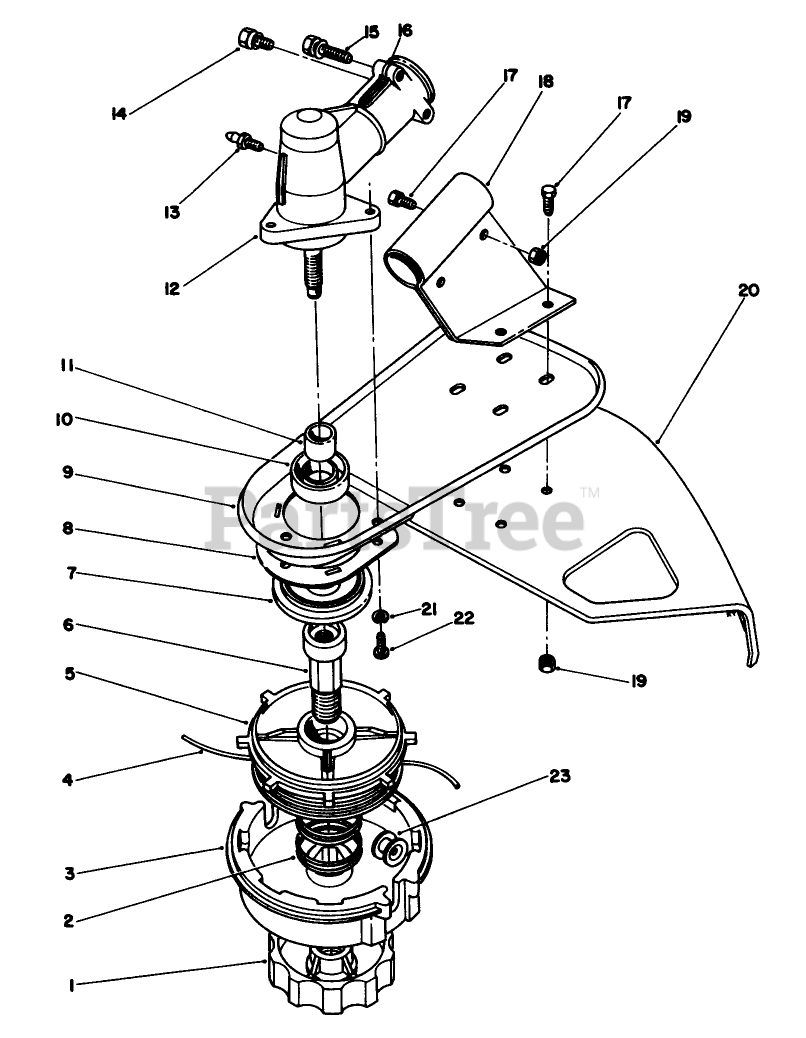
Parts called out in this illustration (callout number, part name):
1	LH KNOB(SERVICE ONLY)
2	SPRING (SERVICE)
3	SPOOL HSG (SERVICE ONLY
5	INNER SPOOL(SERV ONLY)
7	DUST CAP F/W
8	GRASS WRAP GUARD
9	SHIELD SUPPORT *R
10	OIL SEAL
12	GEARBOX
14	HHMS SCREW
17	SCREW-SHH
18	SHIELD BRKT
19	NUT-LOCK, NI
23	EYELET(SERVICE)
